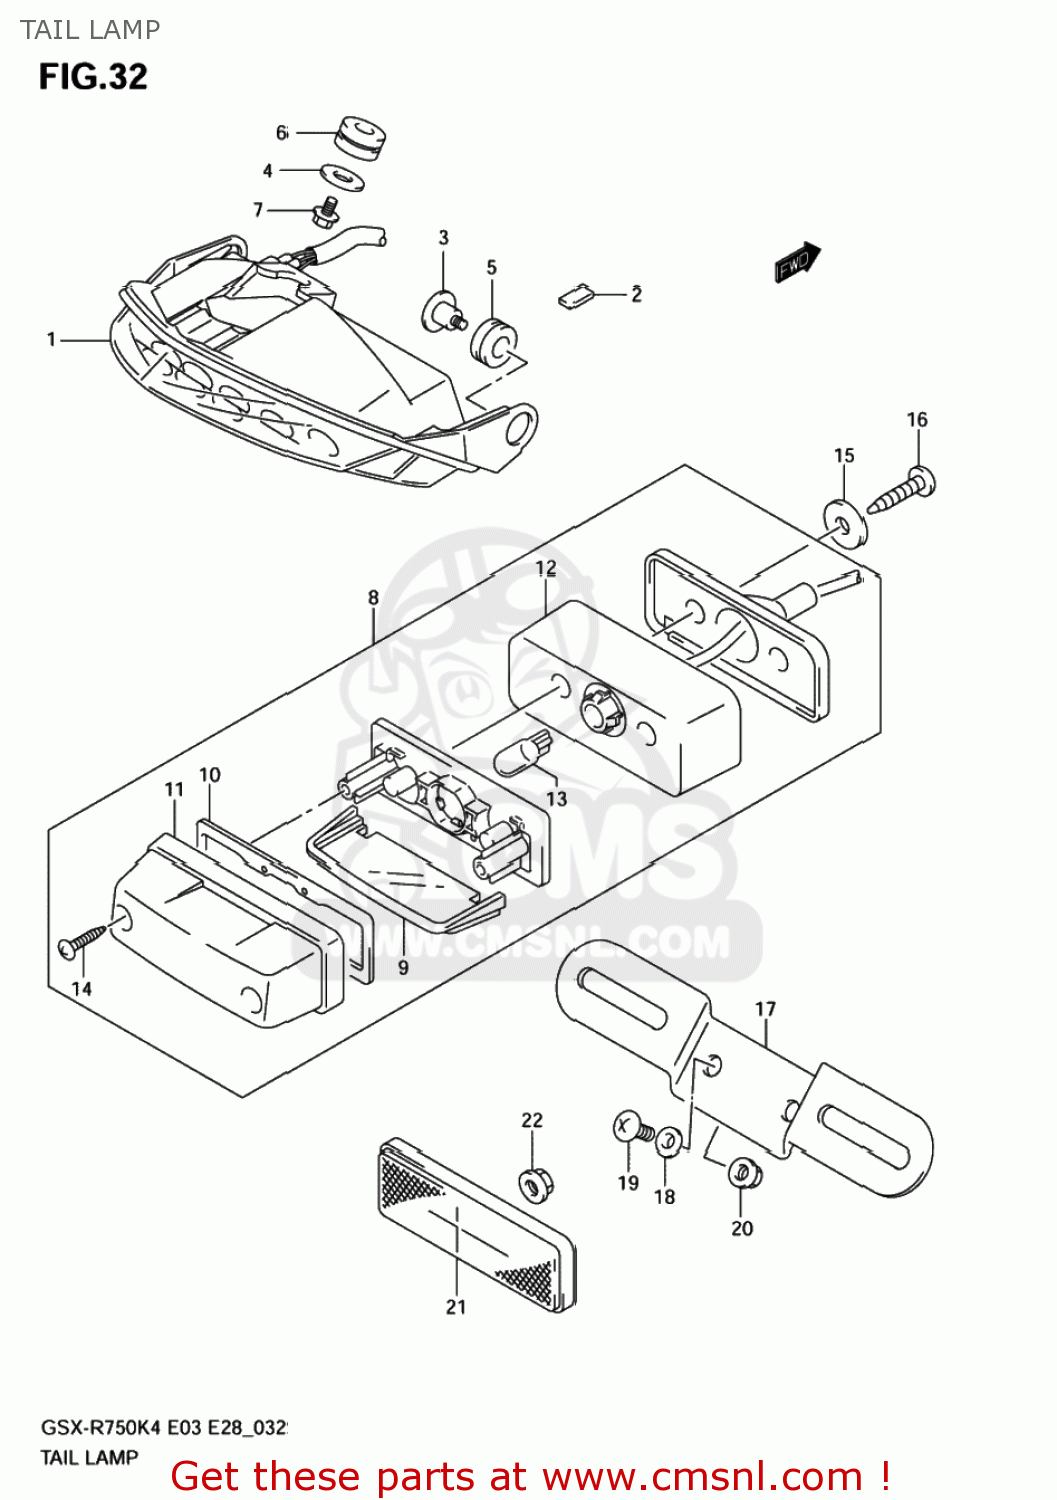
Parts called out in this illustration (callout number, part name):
1	LAMP ASSY,RR COMBINATION
2	PROTECTOR(170X95X3.0)
3	SCREW(5X16.2)
4	WASHER(5.5X20X1.2)
5	CUSHION
6	CUSHION
7	SCREW
8	LAMP ASSY,LICENSE
9	LENS
10	GASKET (NAS)
11	COVER
12	SPACER
13	BULB(12V5W)
14	SCREW
15	WASHER(5.5X20X1.2)
16	SCREW, LICENSE LAMP
17	BRACKET,LICENSE PLATE
18	WASHER(6.5X20X1.6)
19	SCREW
20	NUT
21	REFLECTOR ASSEMBLY,REAR
22	NUT
